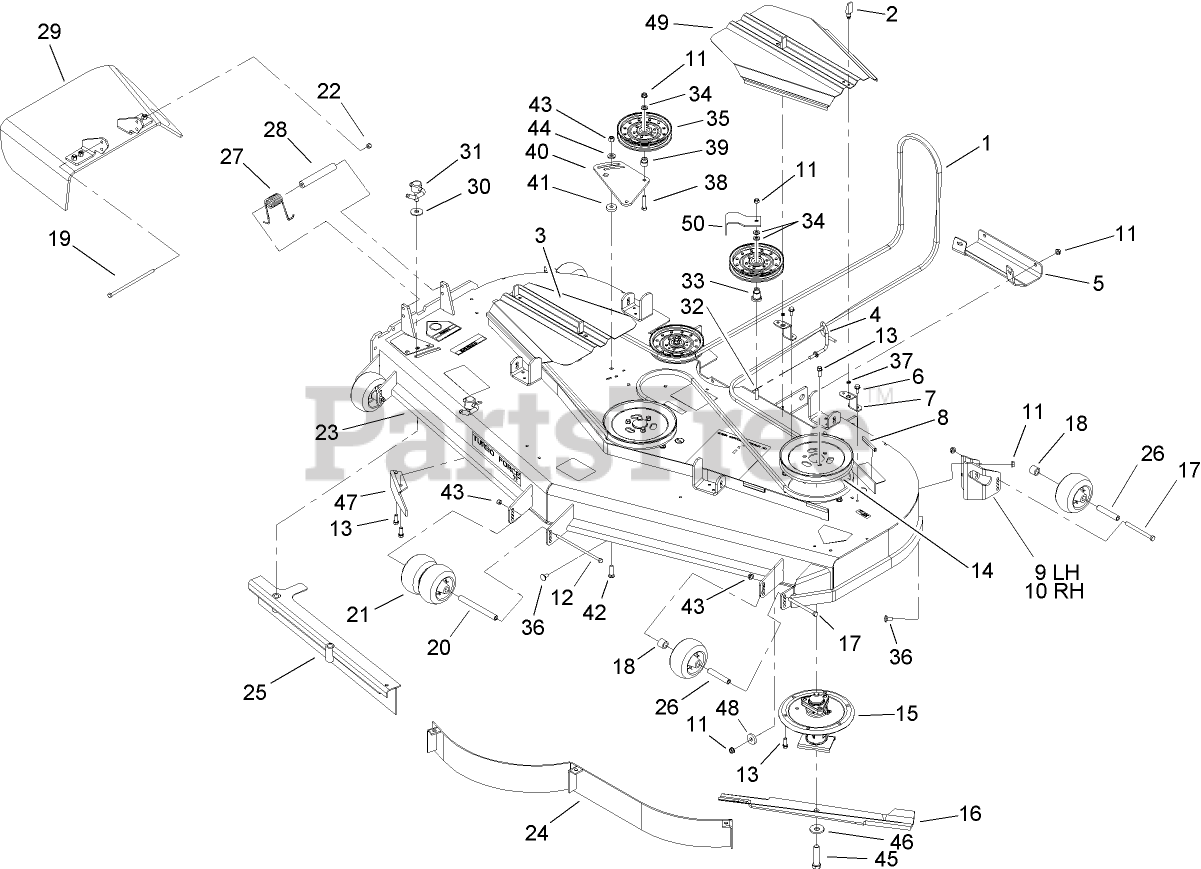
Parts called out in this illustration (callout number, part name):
2	LATCH-SWELL
3	Cover-Belt
4	GUIDE-BELT
5	Plate-Skid
6	SCREW-HWHTF
7	Bracket-Cover
8	STRIP-SEAL
9	MOUNT-WHEEL, LH
10	MOUNT-WHEEL, RH
11	NUT-HHF, WHIZ
12	SCREW-HH
13	SCREW-HWH
14	Pulley
15	Spindle ASM
16	BLADE-HI FLOW, 24.5 INCH
17	SCREW-HH
18	TUBE-SPACER
19	SCREW-HH
20	SPACER-WHEEL
21	ROLLER-SCALP, ANTI
22	NUT-LOCK, NI
23	Deck Decal ASM
26	TUBE-SPANNER
27	SPRING-TORSION
28	SPACER
29	Rubber Deflector ASM
30	WASHER-PLASTIC
31	Lever ASM
32	SCREW-HH
33	MOUNT-PULLEY
34	WASHER-FLAT
35	Idler-Flat
36	SCREW-CARR
37	WASHER
38	SCREW-HH
39	BUSHING-IDLER
40	Plate-Idler
41	Spacer
42	SCREW-CARR
43	NUT-LOCK, NI
44	WASHER-BELLEVILLE
45	Screw-Cap
46	Washer-Blade Bolt, Heavy
47	BAFFLE-DISCHARGE
48	WASHER
49	Cover-Belt
50	GUIDE-BELT
